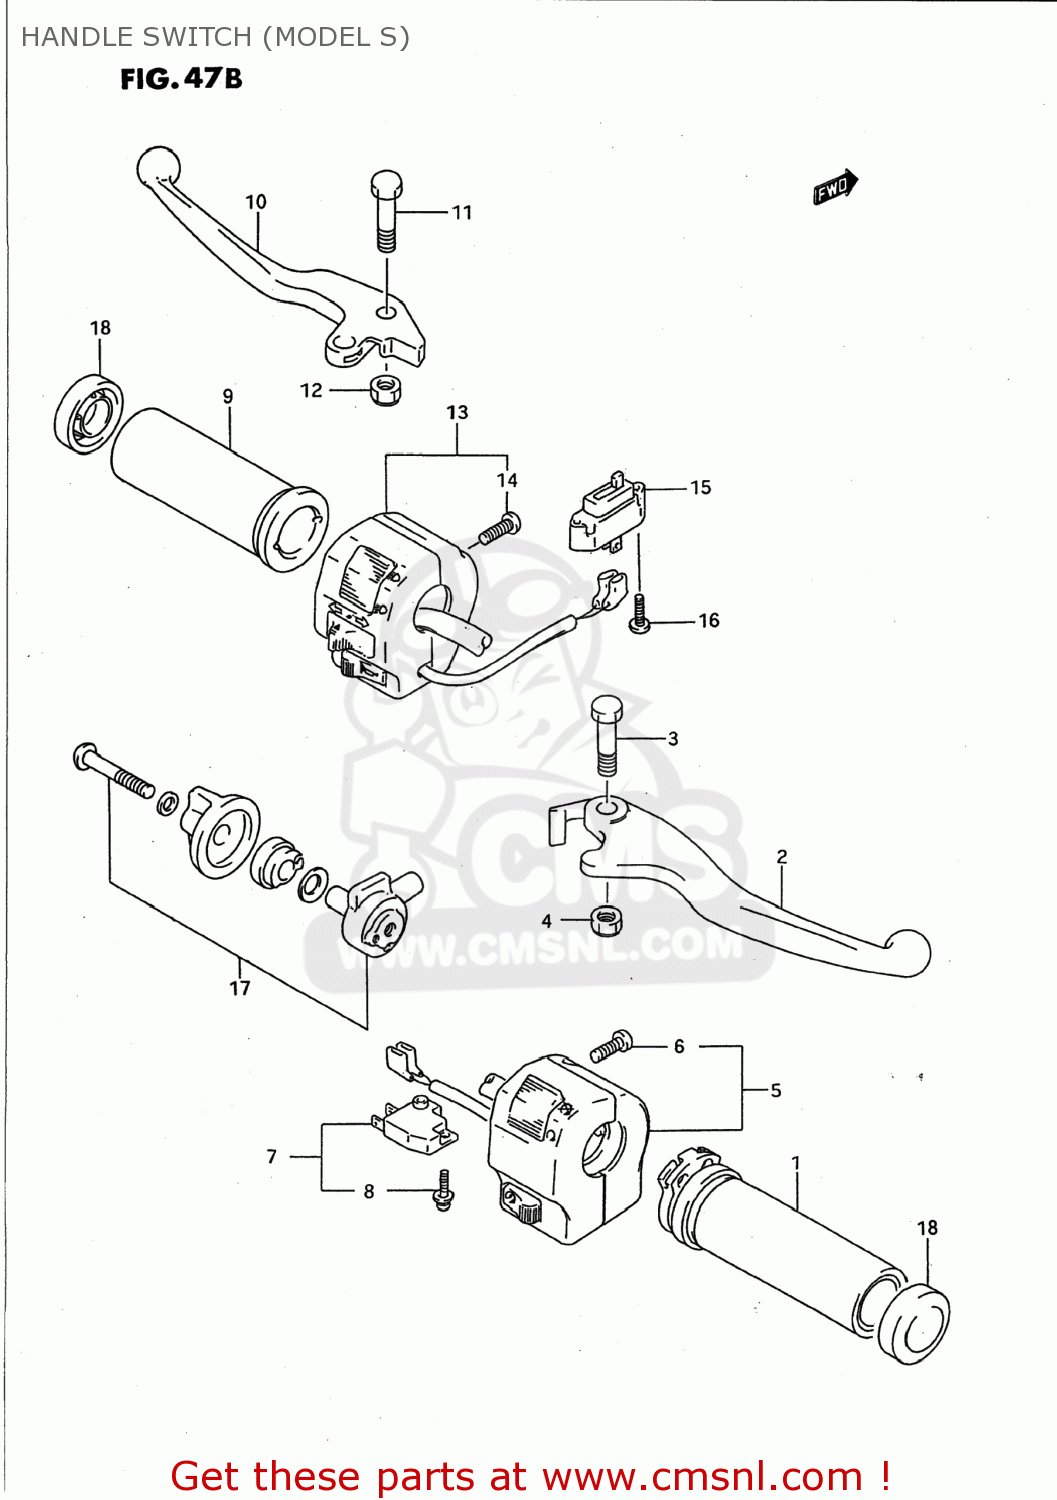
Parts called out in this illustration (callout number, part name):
1	GRIP,THROTTLE
2	LEVER,BRAKE
3	BOLT,LEVER SET
4	NUT 6MM
5	SWITCH ASSEMBLY,HANDLE,RIGHT
6	SCREW
7	SWITCH ASSEMBLY,STOP
8	SCREW
9	GRIP,L
10	LEVER,CLUTCH
11	BOLT,LEVER SET
12	NUT 6MM
13	SWITCH ASSEMBLY,HANDLE,LEFT
14	SCREW
15	SWITCH ASSY,CLUTCH
16	SCREW
17	LEVER ASSEMBLY,STARTER
18	CAP,GRIP END
